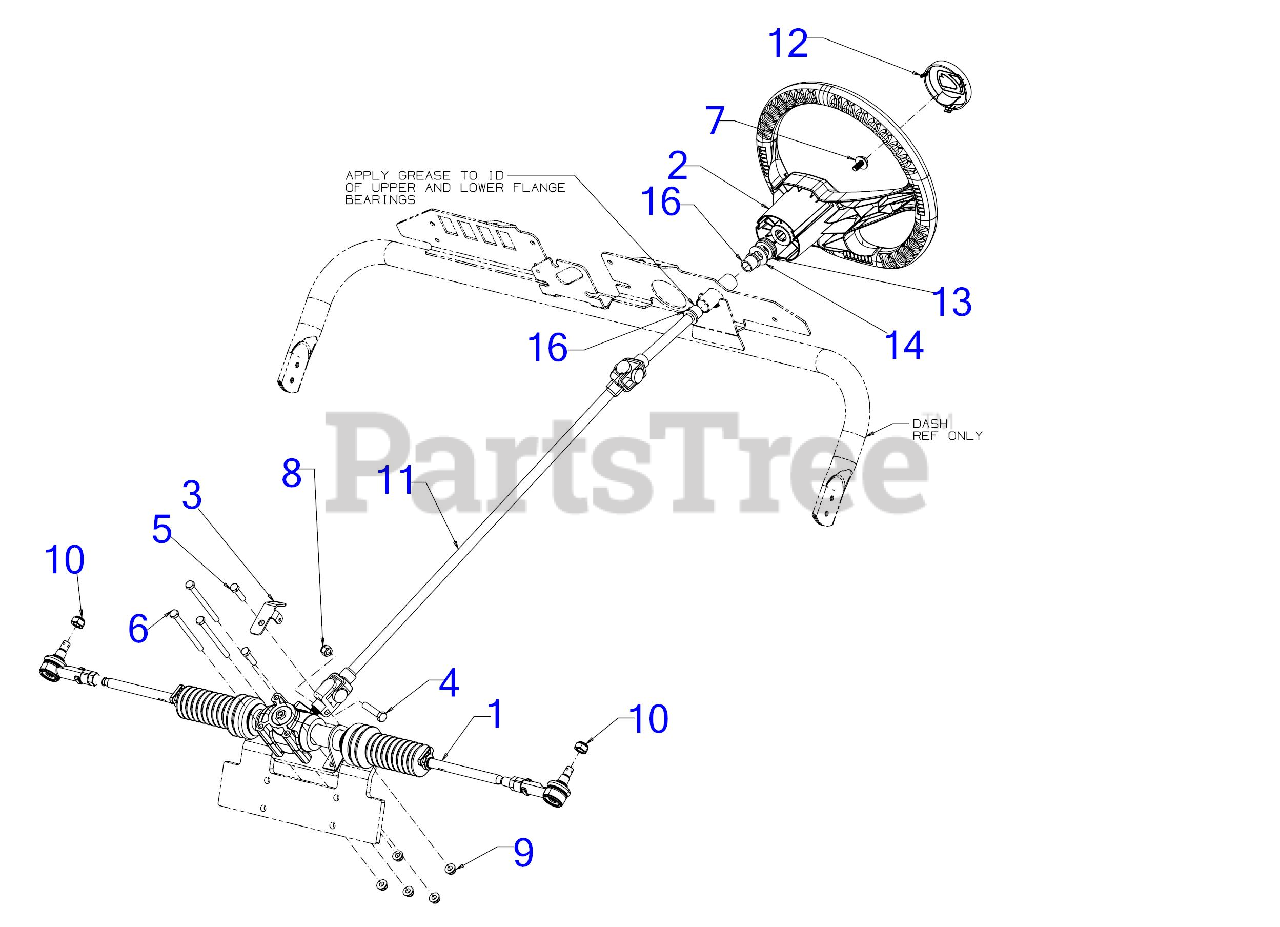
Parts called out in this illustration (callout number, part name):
1	STEERING GEARBOX ASSEMBLY
2	STEERING WHEEL
3	FRONT CABLE MOUNTING BRACKET
4	HEX SCREW 3/8-16 x 1.75 GR5
5	SCREW 5/16-18 x 1.25 GR5
6	SCREW 5/16-18 x 4.00 GR5
7	SCREW 5/16-24 x .85 GR5
8	HEX NUT INS L-3/8-16
9	FLANGE LOCK NUT 5/16-18
11	STEERING SHAFT
12	STEERING WHEEL CAP
13	RUBBER GROMMET
14	FLAT WASHER
16	FLANGE BEARING
